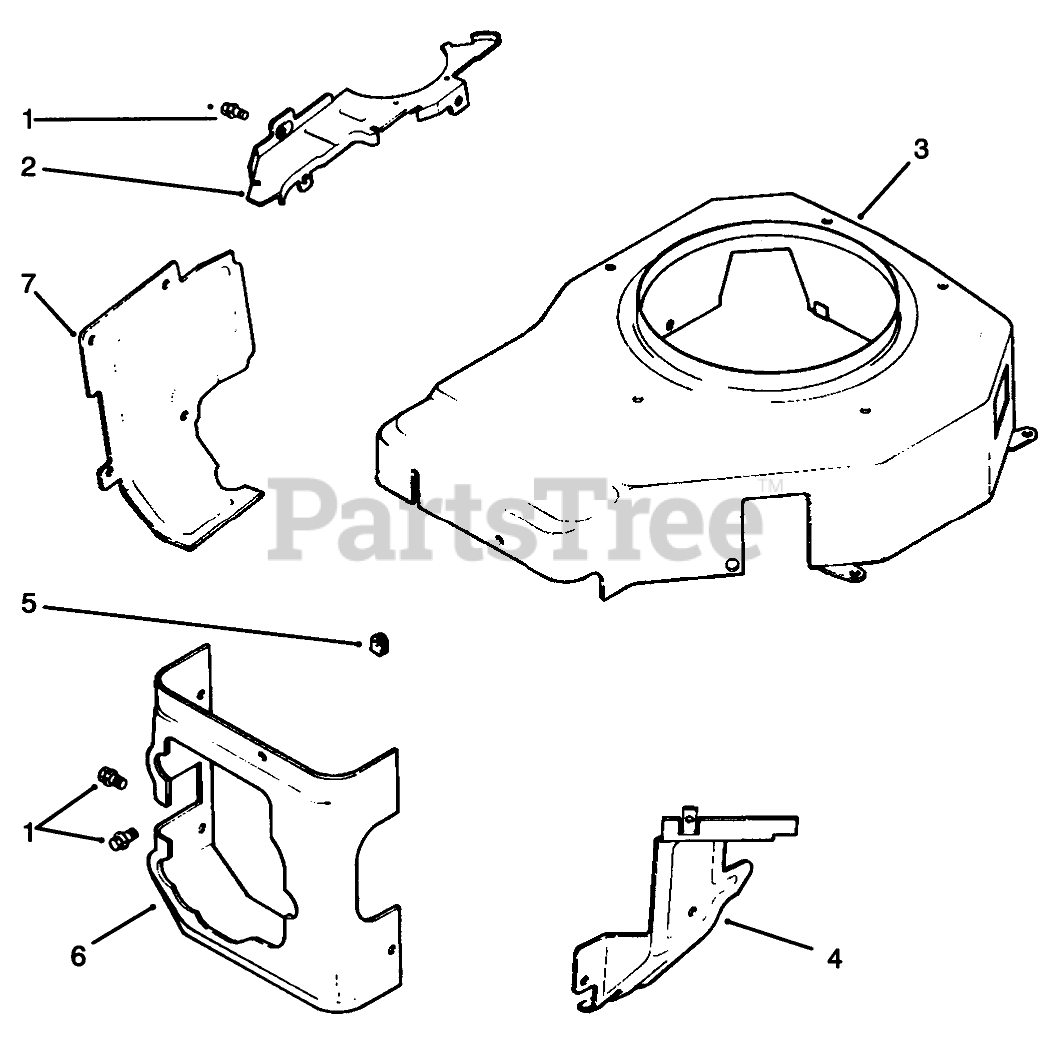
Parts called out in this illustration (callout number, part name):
1	Screw M5x0.8x10 (Only On: 72042, 72043, 72062, 72063)
2	Plate-Blower Housing (Only On: 72042, 72043, 72062, 72063)
3	Housing-Blower (Only On: 72042, 72043, 72062, 72063)
4	Baffle-Carburetor (Only On: 72042, 72043, 72062, 72063)
5	Grommet-Blower Housing (Only On: 72042, 72043, 72062, 72063)
6	Baffle-Cylinder Head (Only On: 72042, 72043, 72062, 72063)
7	Baffle-Cylinder Barrel (Only On: 72042, 72043, 72062, 72063)
